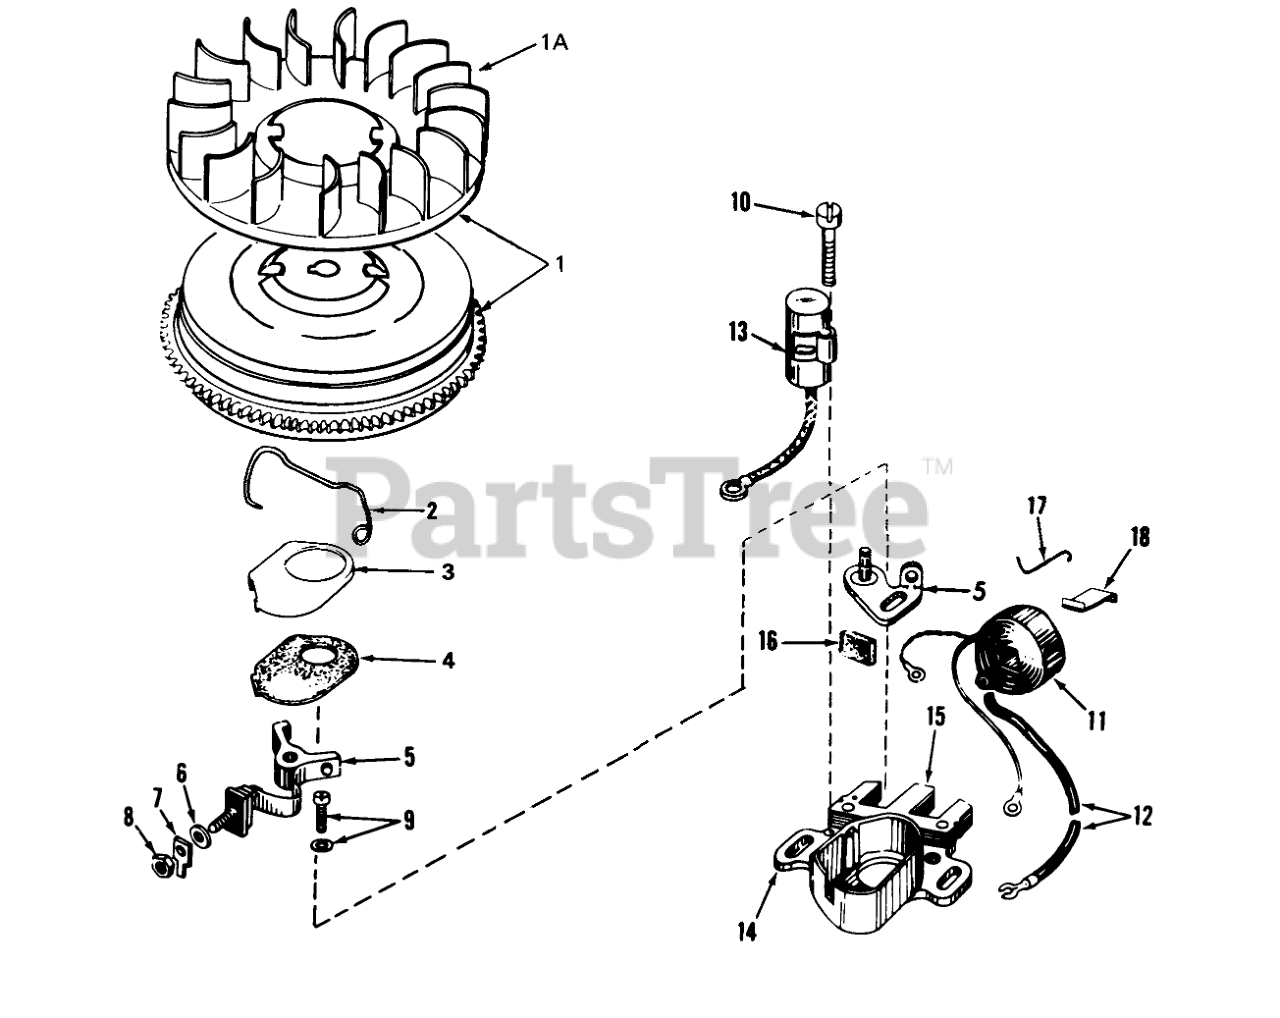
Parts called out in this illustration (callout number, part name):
1	Flywheel (Incl. Ref. #1A)
1A	Fan
2	Spring Breaker Box
3	Cover-Dust
4	Gasket, Dust Cover
5	Breaker Assy.
6	Washer
7	Terminal, Ground
8	DECAL
9	Breaker Screw
10	Condenser Screw
11	Coil Assembly (Incl. Ref. #12)
12	Wire, Lead
13	Condenser
14	Core & Plate
15	Stator Assembly (Incl. Ref. #2 thru 14, 16, 17 & 18)
16	Felt,Cam Wiper
17	Clip, Coil
18	Spring Coil Wedge
